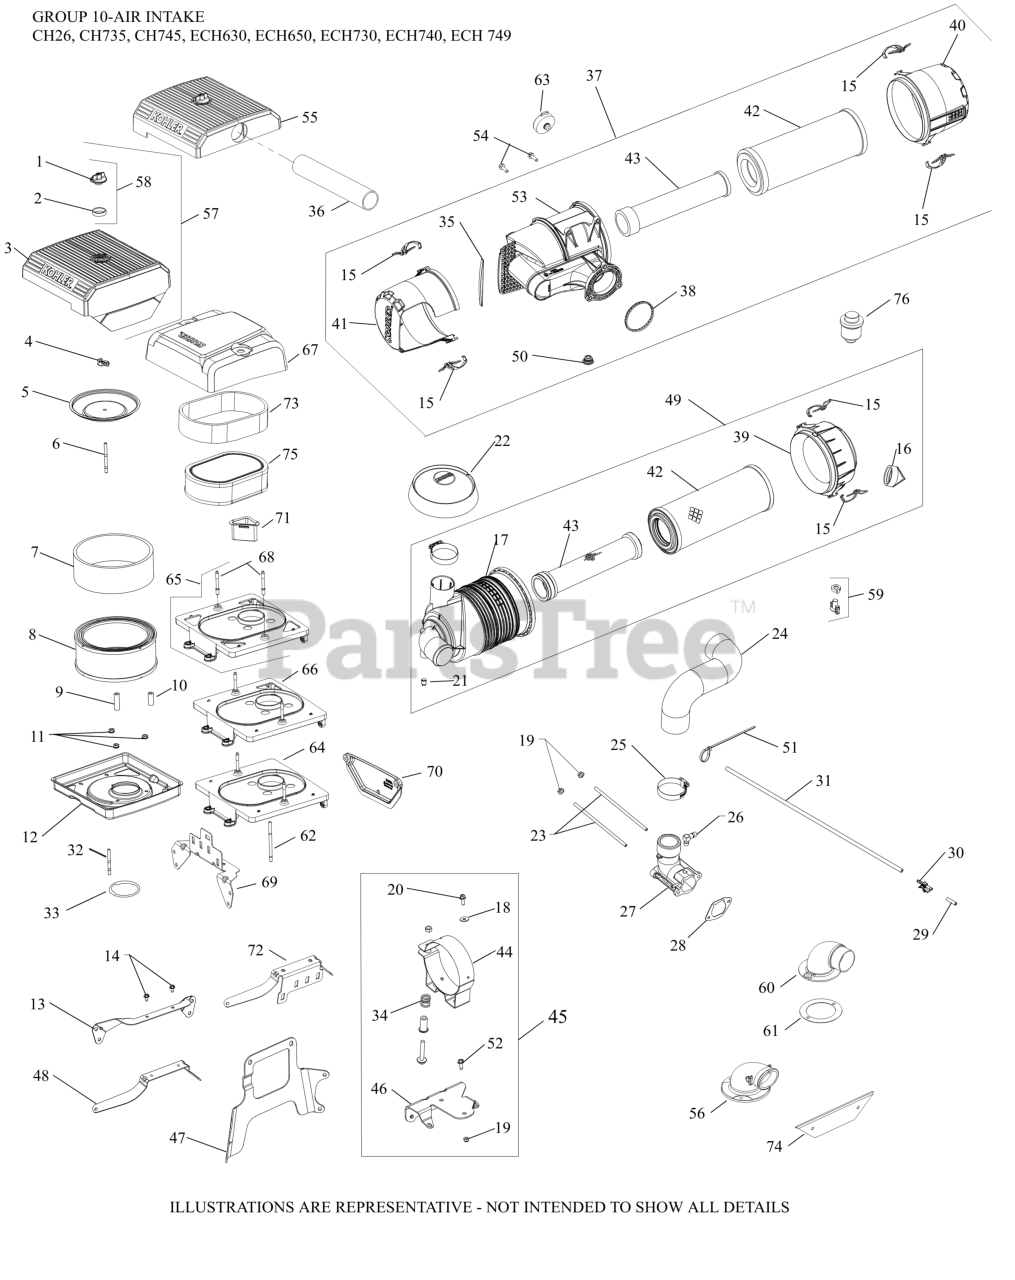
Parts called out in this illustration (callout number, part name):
1	KNOB, COVER
3	COVER, AIR CLEANER
4	NUT, WING
5	COVER, INNER AIR CLEANER
7	PRE CLEANER LOW ELEMENT
8	ELEMENT, AIR CLEANER
12	BASE, AIR CLEANER
13	AIR CLEANER BRACKET
14	SCREW, THREAD FORMING
32	STUD, LOW PROFILE A/C
33	O-RING, AIR CLEANER BASE
57	KIT, AIR CLEANER COVER
58	KIT, KNOB W/SEAL
